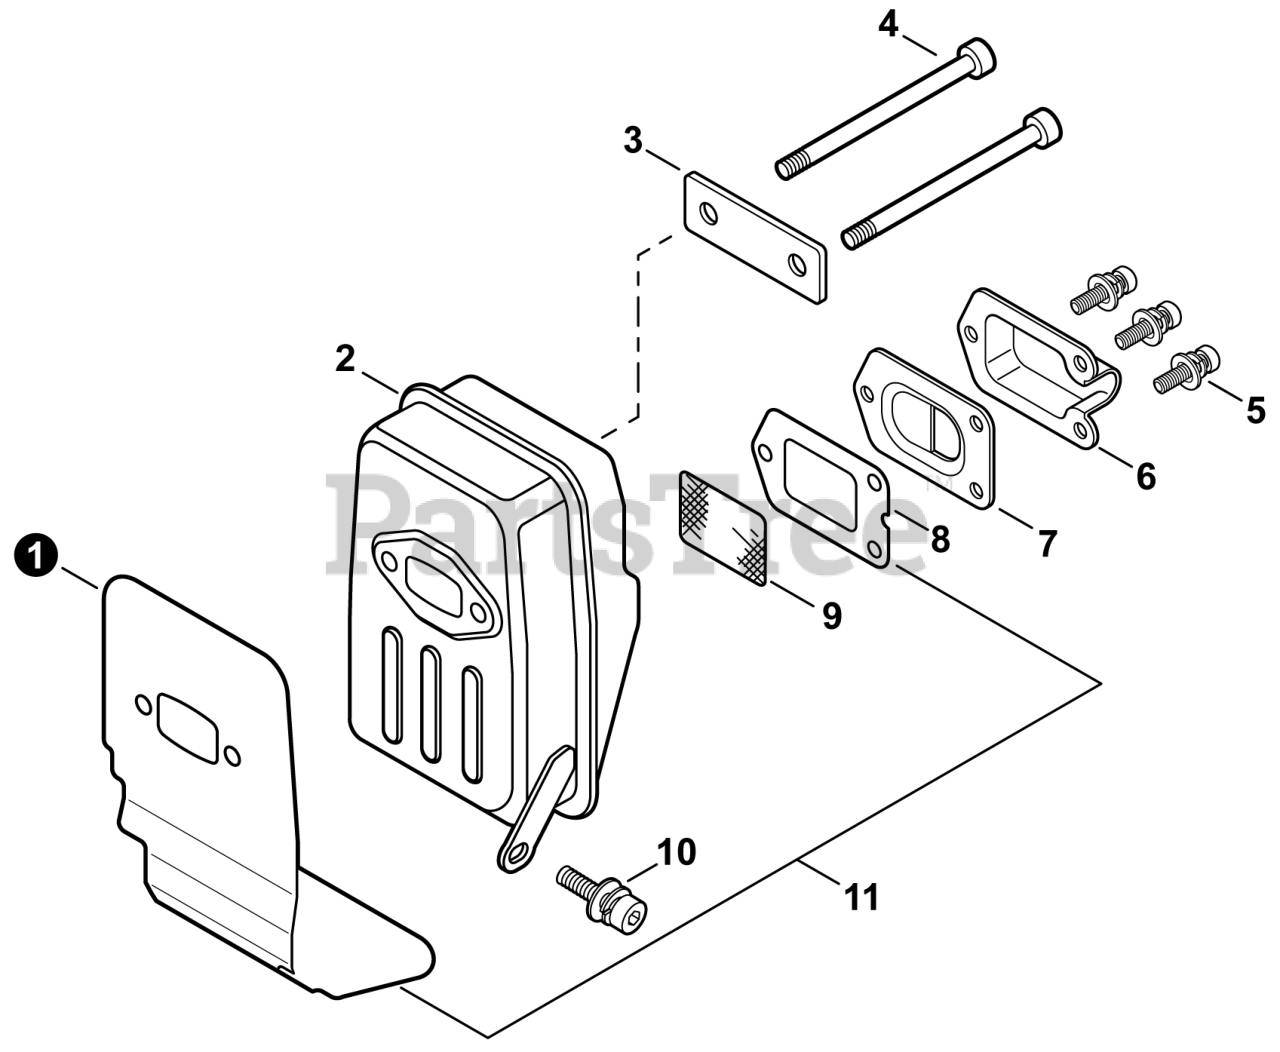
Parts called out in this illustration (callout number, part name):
1	HEAT SHIELD, EXHAUST
2	MUFFLER
3	PLATE, EYE
4	BOLT 6x60
5	SCREW 4x10
6	OUTLET, EXHAUST
7	GUIDE, EXHAUST
8	GASKET, EXHAUST
9	SCREEN, SPARK ARRESTER
10	BOLT 5x12
11	GASKET KIT
